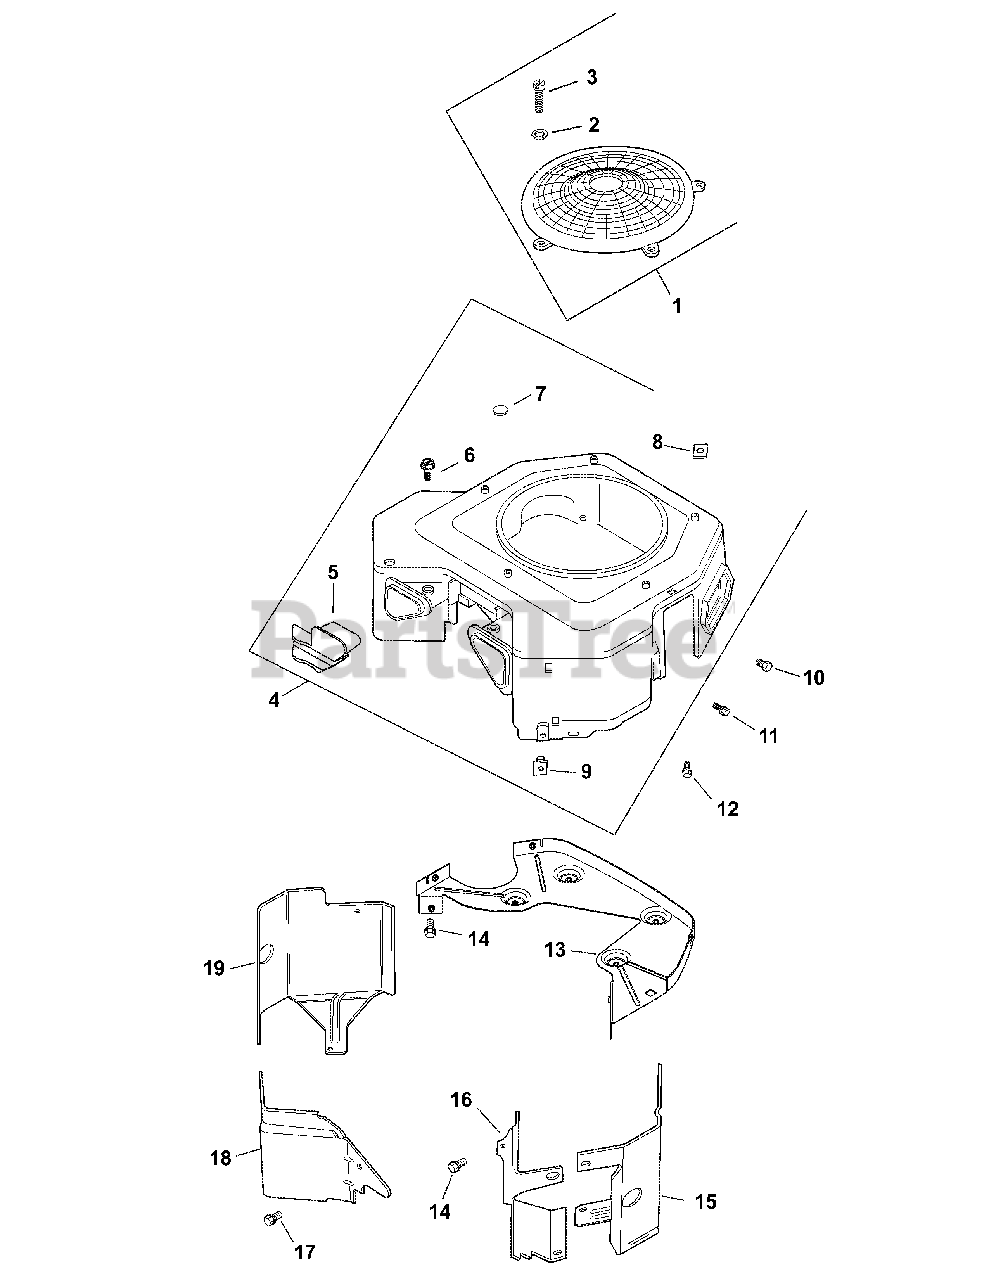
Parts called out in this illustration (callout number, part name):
1	Kit, Fixed Guard
2	Washer, Flat 7/32
3	Screw, LBD SCKT Pan M5x0.8x10
4	Kit, Blower Housing Assembly
5	Cover, Blower Housing
6	Screw, Wsh Hd Tap #8-18 x 1/2"
7	Plug, Button 9/16
10	Screw, FLG THD FRM M5 x .8 x 16
11	Screw, FLG THD FRM M5 x .8 x 16
12	Screw, FLG THD FRM M5 x .8 x 20
13	Kit, Backing Plate
14	Screw, FLG THD FRM M6 x 1.0 x 16
15	Kit, Cyl Baffle-#2 Side
16	Baffle, Valley-#2 Side
17	Screw, FLG THD FRM M5 x .8 x 10
18	Baffle, Valley #1 Side
19	Kit, Cyl Barrel - #1 Side
